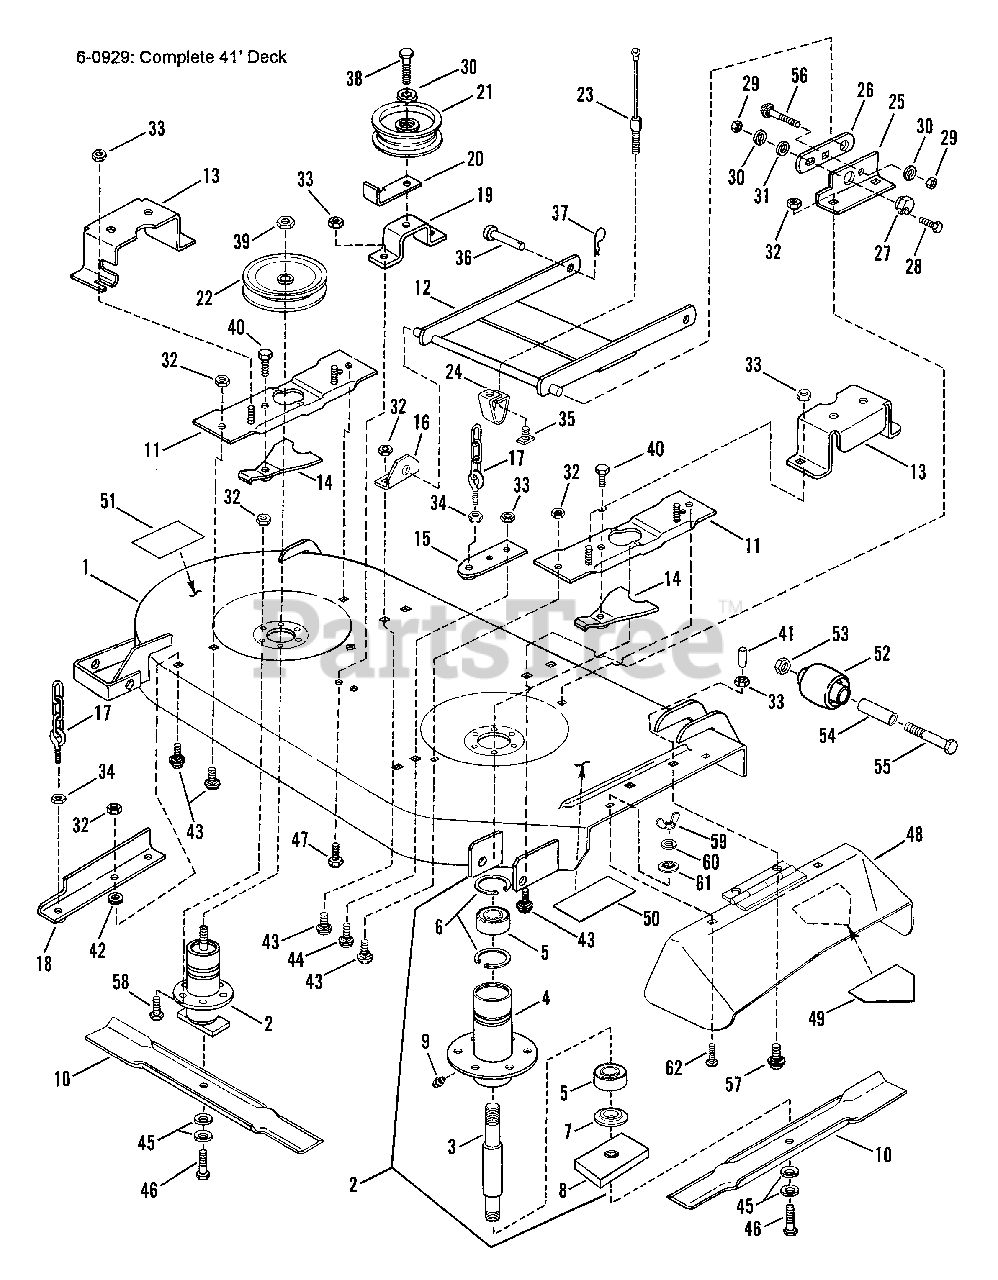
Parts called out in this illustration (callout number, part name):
1	DECK, Mower 41"
2	ASSEMBLY, Spindle
3	SPINDLE 6.5"
4	HOUSING, Spindle
5	BEARING, Spindle
6	RING, Retaining
7	WASHER, Spindle
8	HOLDER, Blade
9	FITTING, Lube (Press fit for .187 hole-no ball)
10	BLADE, 21" Cutter
11	ASSEMBLY, Rear Support
12	ASSEMBLY, Front Hanger
13	GUARD, Pulley
14	ASSEMBLY, Spindle Lock
15	ASSEMBLY, Chain Support
16	BRACKET, Front Left Hanger
17	ASSEMBLY, Bolt Chain
18	ASSEMBLY, Rear Support
19	BRACKET, Idler Mount
20	GUIDE, Belt
21	PULLEY, Idler
22	PULLEY, Spindle
23	CABLE, Front Lift
24	BRACKET, Front Lift Arm Hanger
25	BRACKET, Front Right
26	LINK, Adjustment
27	RING, Adjustment
28	SCREW, 318-16x1" Hex Head Cap
29	NUT, 3/8-16 Hex
30	WASHER, 3/8 Split Lock
31	WASHER, 3/8" Flat
32	NUT, 3/8-16 Hex Flange Lock
33	NUT, 5/16-18 Hex Flange Lock
34	NUT, 3/8-16 Hex Jam
35	T-NUT, 5/16-18
36	PIN, 1/2x1-3/8" Clevis
37	HAIRPIN, Cotter
38	SCREW, 3/8-16x1-1/2" Hex Cap
39	NUT, 3/4-16 Hex Jam
40	BOLT, 318-16x1" Hex Flange Lock
41	CAP, Vinyl
42	WASHER, 7/16 Flat
43	BOLT, 3/8-16x3/4" Carriage
44	BOLT, 5/16-18x3/4" Carriage
45	WASHER, 13/32x1-13/32" Dia. Cone
46	SCREW, 3/8-24x1-1/4" Hex Cap
47	BOLT, 5/16-18x3/4" Hex Flange Lock
48	DEFLECTOR, Side Chute
49	DECAL, Danger
50	DECAL, Caution (Deflector in Place)
51	DECAL, Caution (Rotating Blades)
52	WHEEL, Gage
53	LOCKNUT, 3/8-24 Hex
54	SPACER
55	SCREW, 3/8-24x3-3/4" Hex Hd. Cap
56	BOLT, 3/8-16x3/4" Short Neck Carriage
57	BOLT, 5/16-18x1" Short Neck Carriage
58	BOLT, 3/8-16x3/4" Hex Flange Lock
59	WING-NUT, 5/16-18
60	WASHER, 5/16 Split Lock
61	RETAINER, 5/16 Bolt
62	BOLT, 5/16-18x5/8" Carriage
60929	ASSEMBLY, 41" Deck Complete
